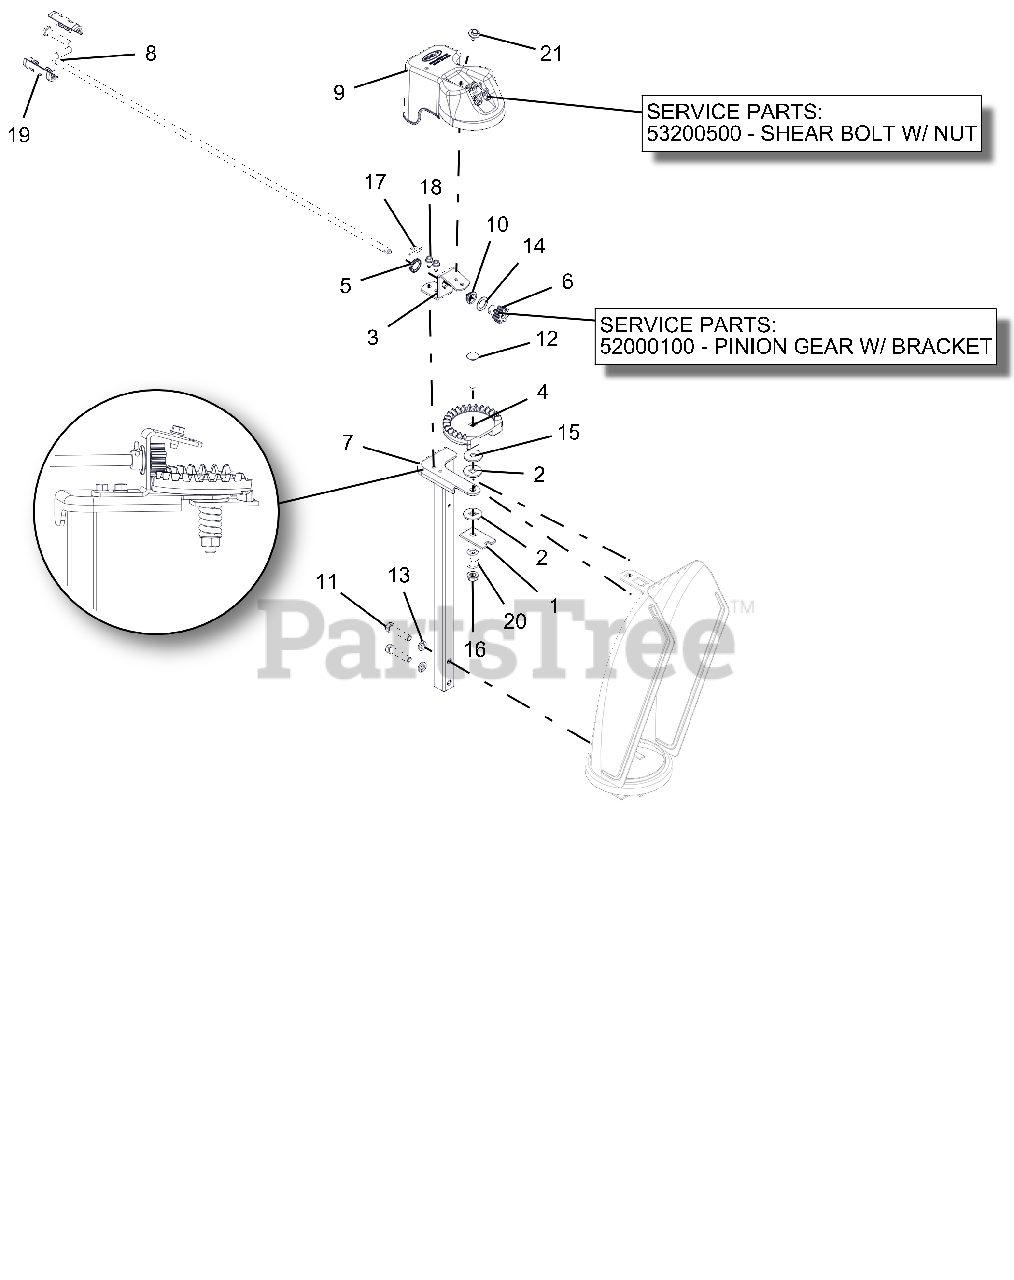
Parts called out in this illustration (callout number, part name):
1	PLATE, FRICTION
2	FRICTION WASHER
3	BRACKET, PINION GEAR
4	CHUTE GEAR
5	PUSHNUT .625
6	PINION GEAR - CHUTE
6	PINION GEAR W/BRACKET
7	CHUTE PEDESTAL, TALL COMPACT
8	ROD, CHUTE CRANK, COMP&SNOTEK
9	GEAR COVER ASSY SM SHEAR BOLT
9	SHEAR BOLT WITH NUT
10	BUSHING, POLYLINER-.63 SNAPIN
11	@BLT-HEX .38-16X1.75 GR5 YWZC
12	@BLT-RDHDSQNK .38-16X2.50 G5YZ
13	@WSHR-LK .38X.094 REG YWZC
14	WSHR-THRST .625 X 1.0 X .03
15	@WSHR-FL-STL .406X1.25X.10 ZC
16	@NUT-LK-TOP-FLG .38-16 YWZC
17	PIN, SPRING CLIP
18	SCR-TAP .25-20X.50 HWH TR YWZ
19	KNOB, CHUTE CRANK - SNAP GRAY
20	SG-COMP .187X.56X1.62
21	SCR-TAP .25-20X.50 LGHWH TR YZ
